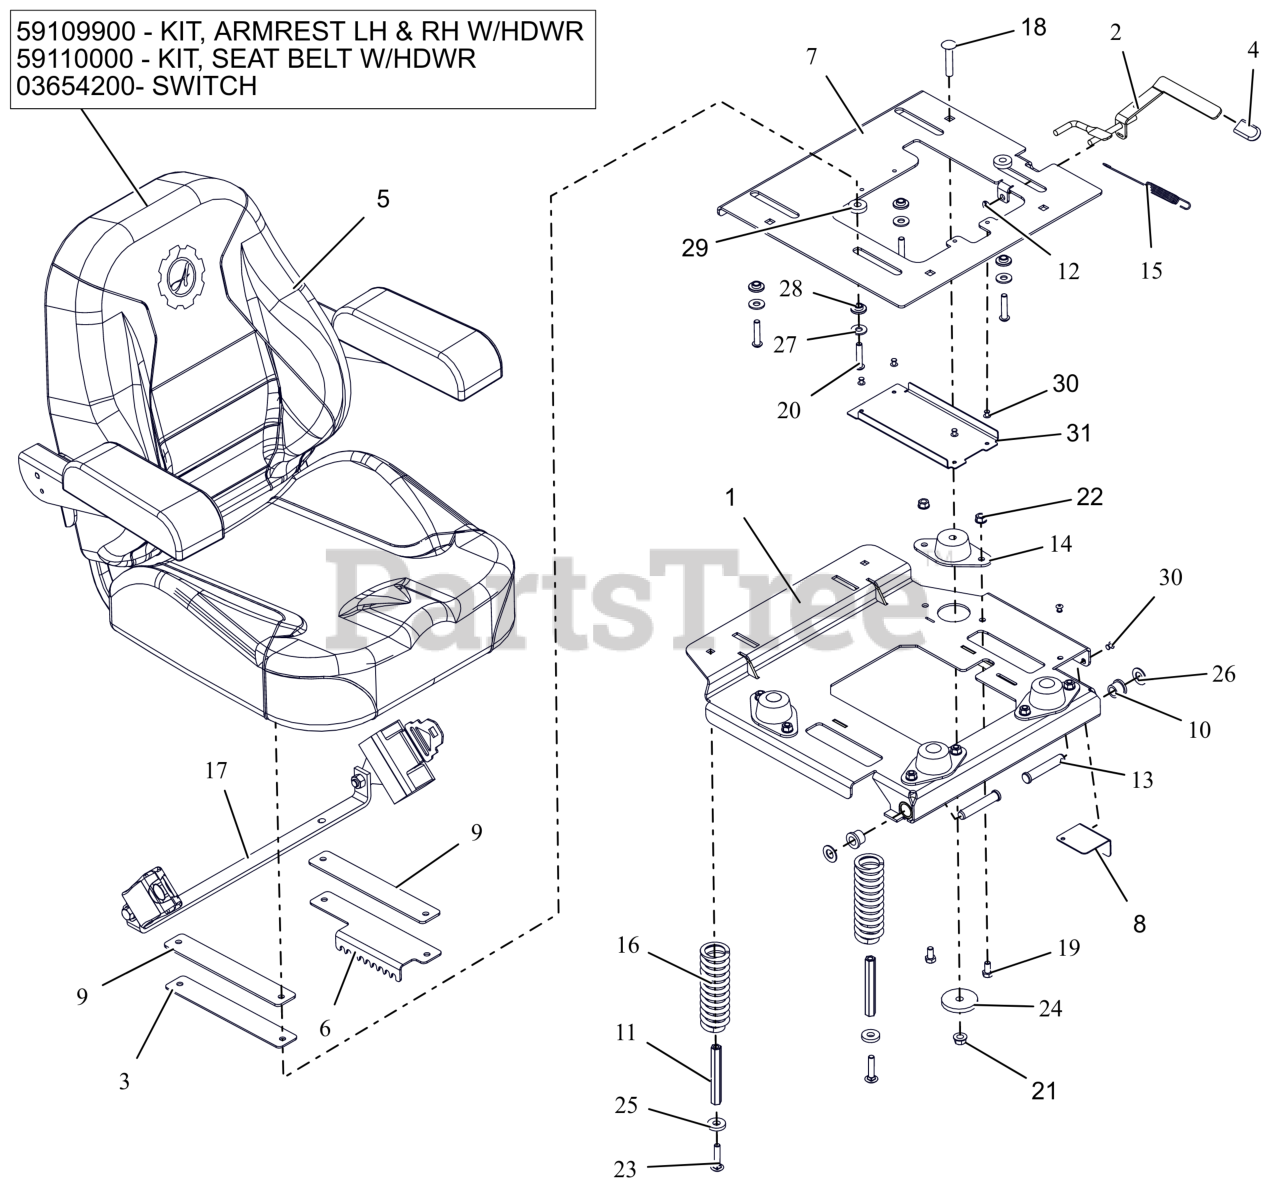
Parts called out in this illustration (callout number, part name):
1	WLDMT, ISO MTG PLATE (BLACK)
2	WLDMT, SEAT SLIDE LEVER
3	PLATE, ADJUSTABLE SEAT SLIDE
4	GRIP, SEAT LEVER, GREY
5	SEAT, APEX
5	KIT, LH&RH ARM REST-05007300
5	KIT-SEAT BELT REPLACE-05007300
5	SWITCH- SEAT
6	PLATE, HD SEAT ADJUSTMENT
7	PLATE, SEAT MOUNTING (ISO KIT) (ORANGE)
8	GUARD, SEAT FAN (SH)(BLACK)
9	SPACER, SEAT
10	BSHG, FLG .516X.750X.625X.937
11	NUT, COUPLING 5/16X18 X 3.75
12	NUT-PUSH .312
13	PIN-CLIC .50X2.70X2.31 -ZCC
14	MOUNT, FAIL-SAFE COMPRESSION
15	SG-TENS .06X.482X5.35
16	SPRING, COMPRESSION SEAT 224LB
17	KIT-SEAT BELT REPLACE-05007300
18	BLT,RHSSN.375-16X2.00 G5 ZCC
19	BLT, HEX .31-18X.625 G5 ZCC
20	BLT,SHCS-BTN .31-18X1.50 ZCC
21	NUT-LK-CTR-FLG .375-16 GF ZCC
22	NUT,LK-CTR-FLG .31-18 GF ZCC
23	BLT,RHSN .31-18X1.50 G5 ZCC
24	WSHR-FL-STL 0.406X2X0.25 ZCC
25	WSHR, FLT .406X1.00X.188 ZCC
26	WSHR, FLT .531X1.00X.063 ZCC
27	WSHR,FLT .375X.875X.083 ZCC
28	BSHG-FLG .325X.499X.3X.875
29	WSHR, FLT .390X1.00X.250 ZCC
30	RIVET, .1875 AL/AL .126-.250
31	PLATE, SEAT GUARD (BLACK)
